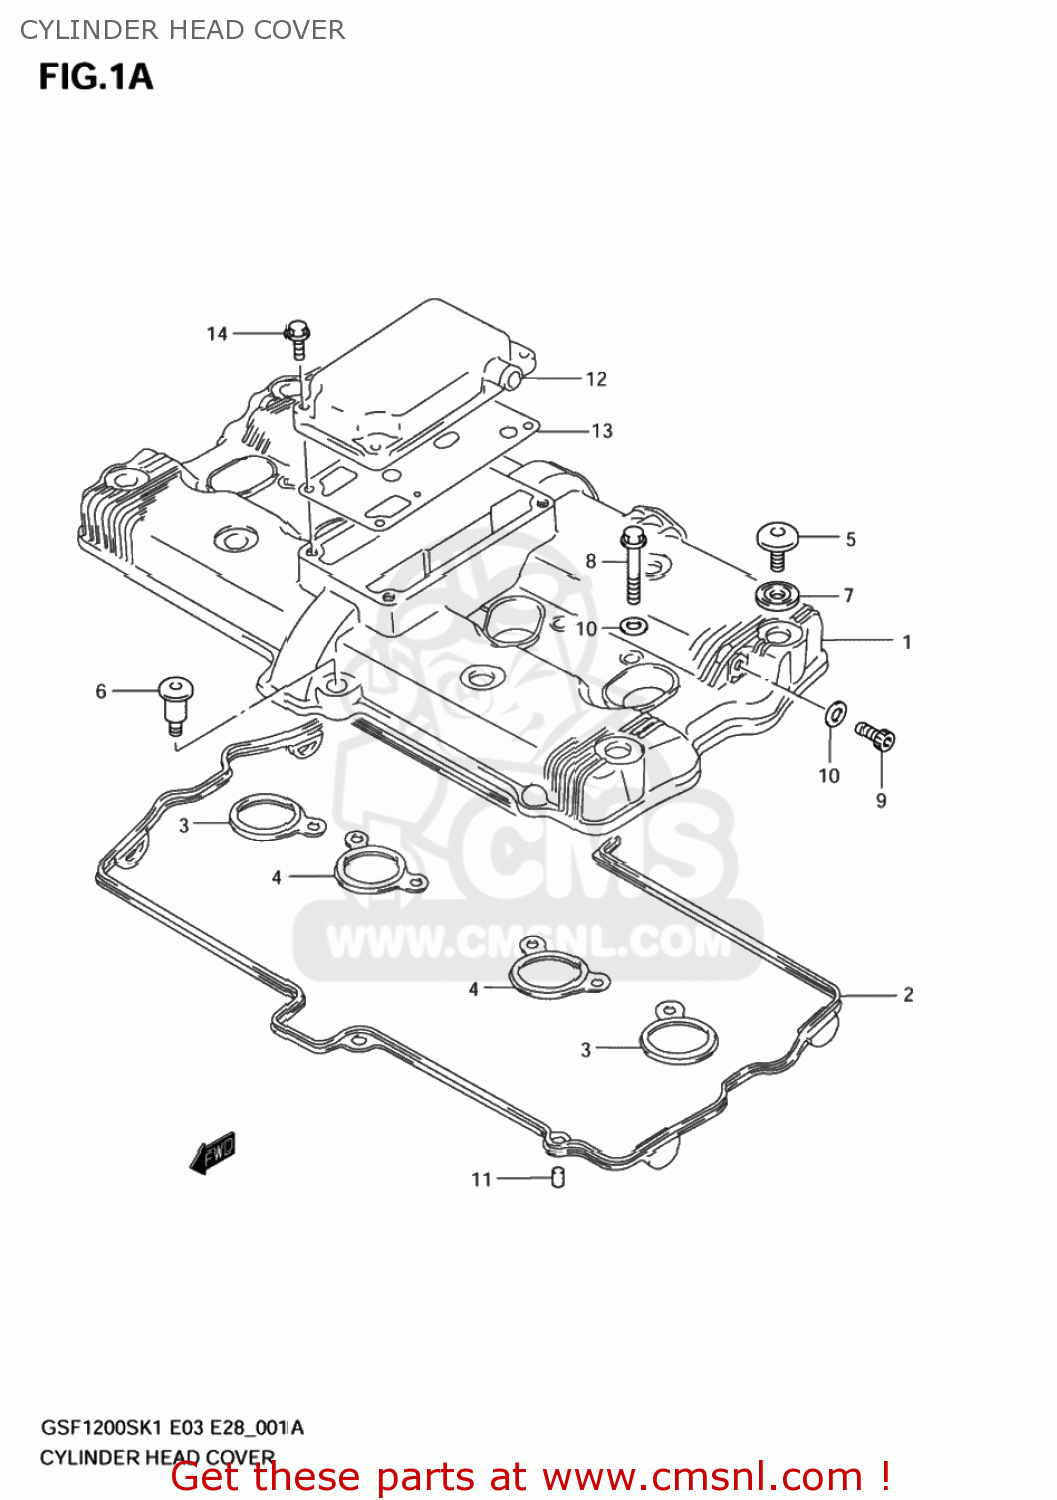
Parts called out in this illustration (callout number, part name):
1	COVER,CYLINDER HEAD
2	GASKET,CYLINDER HEAD COVER (NAS)
3	GASKET,HEAD COVER NO.2 (NAS)
4	GASKET,HEAD COVER NO.3 (NAS)
5	BOLT(7X17.5)
6	BOLT(7X31)
7	WASHER(10.6X25.5X2.3)
8	BOLT,HEAD COVER UNION(8X35)
9	PLUG
10	GASKET(8.2X16X1) (NAS)
11	PIN
12	COVER,BREATHER
13	GASKET,BREATHER COVER
14	BOLT
